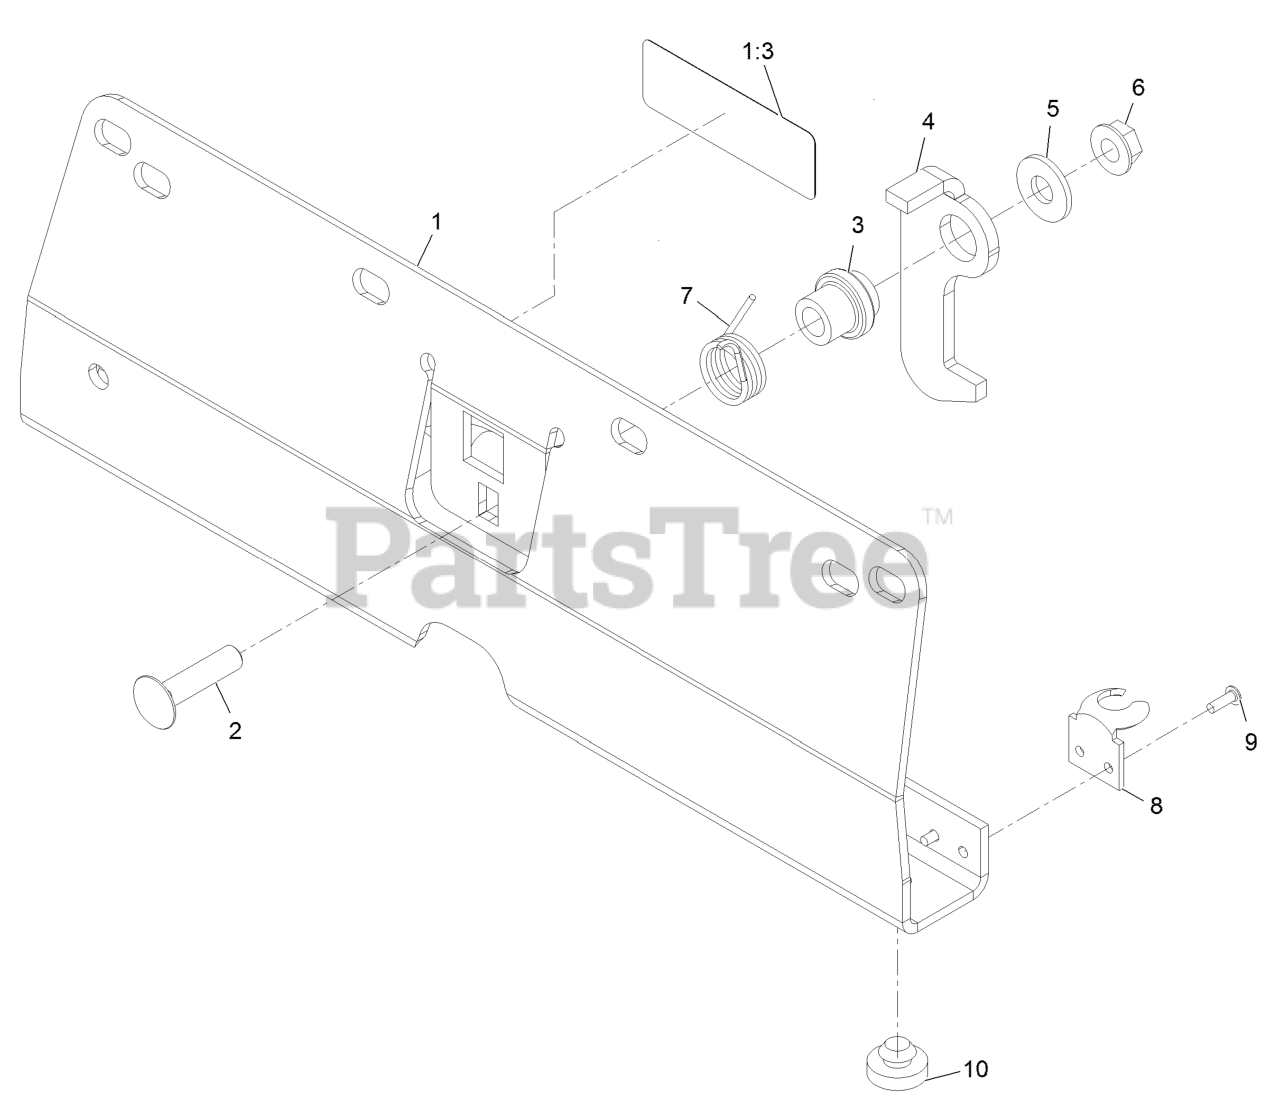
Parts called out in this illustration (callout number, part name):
1	ASM,LATCH PLATE S.O.
1:3	DECAL-WARNING, PINCH POIN
2	SCREW-CARR
3	BUSHING-LATCH, SEAT
4	HOOK,LATCH
5	WASHER-FLAT
7	SPRING,LATCH
8	KEEPER
